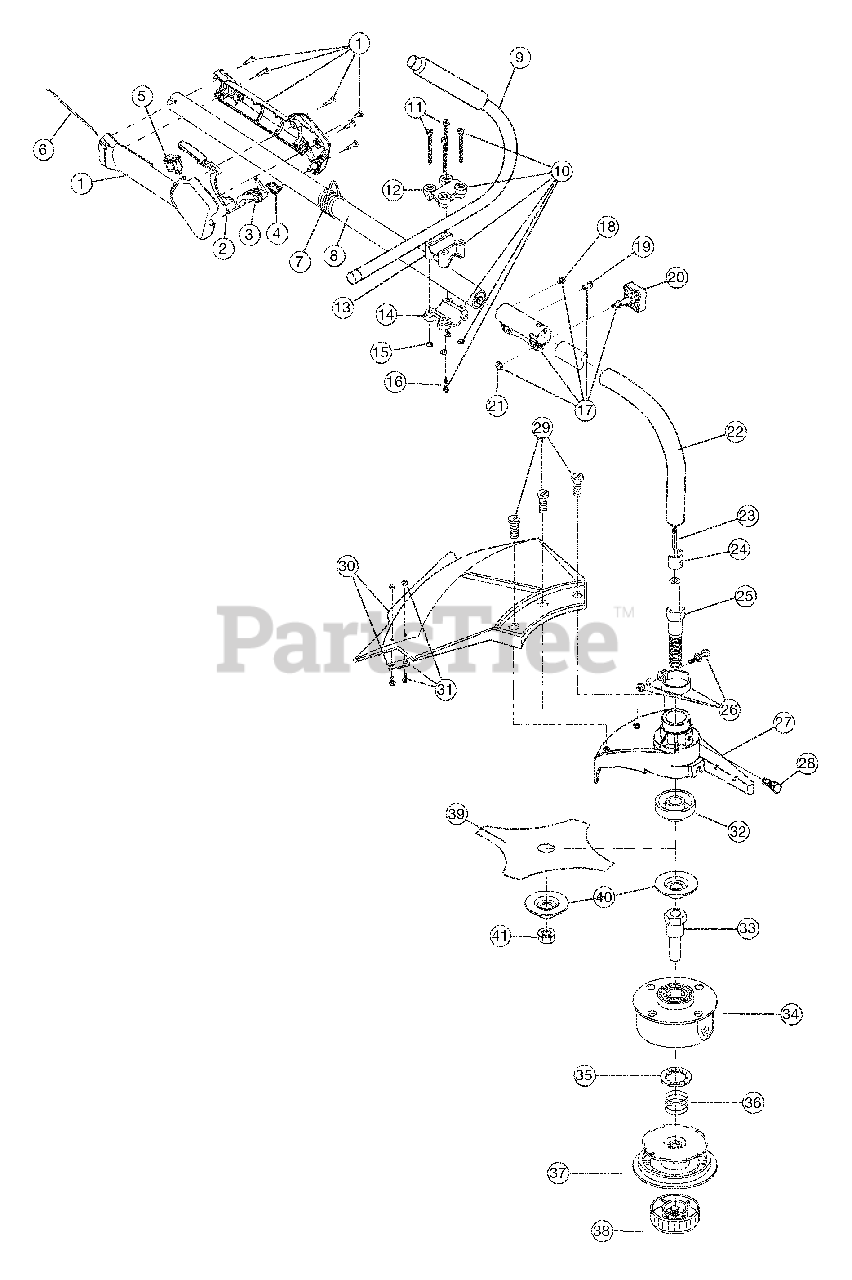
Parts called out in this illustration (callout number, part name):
1	Throttle Housing and Trigger Assembly
2	Throttle Trigger Lock-Out
3	Throttle Trigger
4	Throttle Trigger Spring
5	Switch Assembly
6	Throttle Cable Assembly
7	Harness Clip
8	Upper Drive Shaft Housing Assembly
9	J-Handle Assembly
10	Handle Bracket Assembly
12	Upper Handle Clamp
13	Middle Handle Clamp
14	Lower Handle Clamp
16	Anti-Rotation Screw
17	EZ-Link Coupler
20	Adjustment Knob
21	Knob Retaining Nut
22	Lower Drive Shaft Housing Assembly
23	Lower Flexible Drive Shaft
24	Retainer Sleeve
25	Output Shaft
26	Clamp Assembly
27	Bearing Housing Assembly
28	Mounting Bolt
29	Shield Mounting Screw
30	Shield and Blade Assembly
31	Blade Assembly
32	Shaft Bushing
33	Spool Shaft
34	Outer Spool
35	Retainer
36	Spring
37	Inner Reel
38	Bump Head Knob Assembly
39	4-Tooth Blade
40	Retaining Washer
